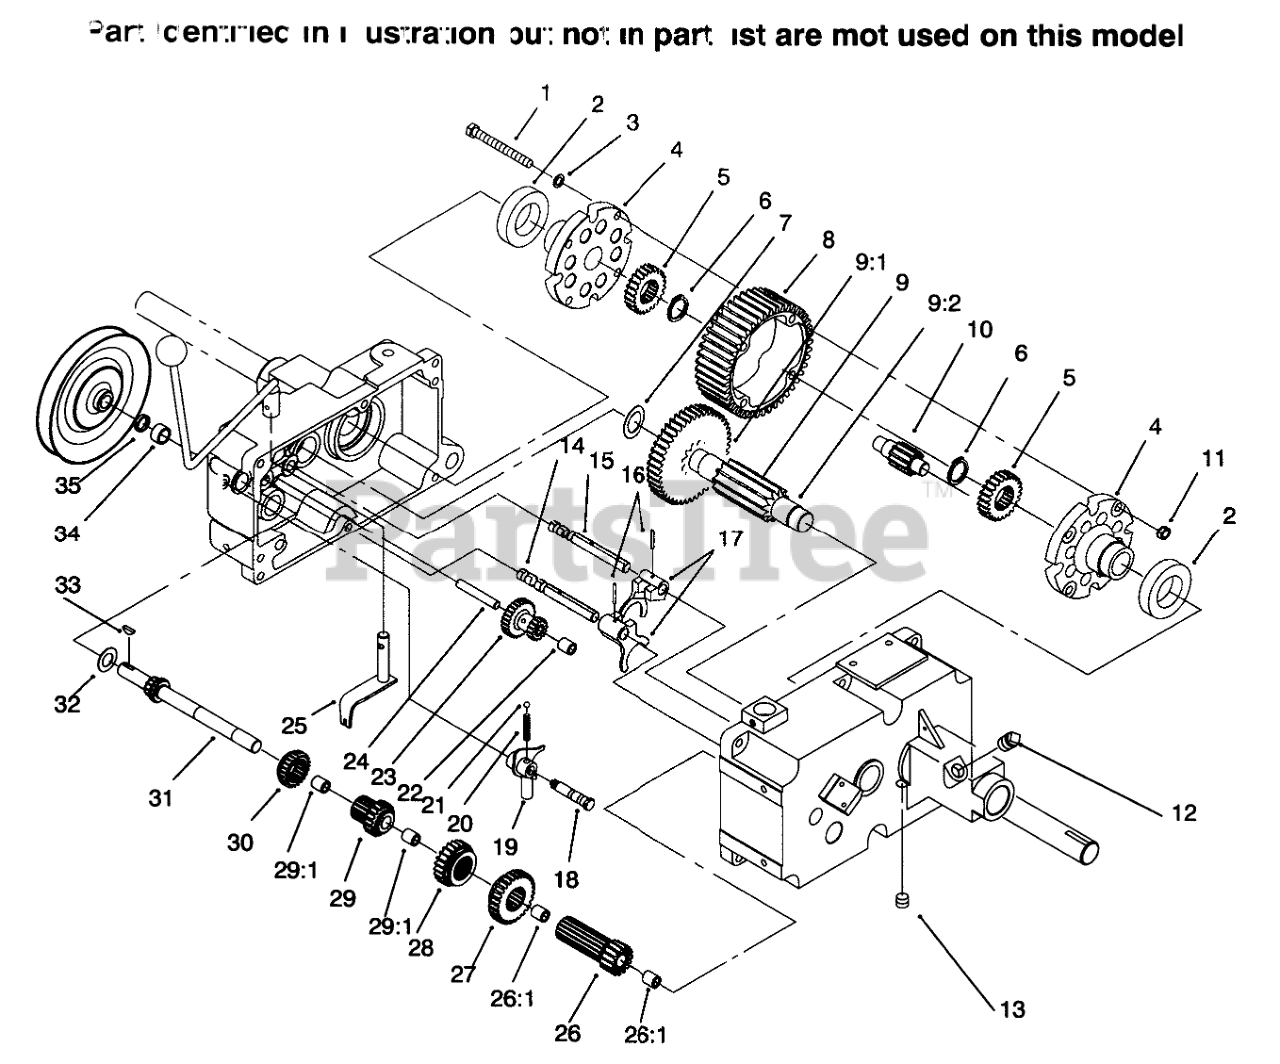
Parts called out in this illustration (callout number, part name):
1	BOLT-HEX
2	BEARING-BALL
3	WASHER
4	END CAP-DIFFERENTIAL
5	GEAR-AXLE DIFFERENTIAL
6	RING-SNAP
7	WASHER-THRUST
8	GEAR-DIFFERENTIAL RING, 43T
9	GEAR ASM
9:2	PINION SHAFT
10	GEAR-PINION, 11T
12	PLUG-PIPE, SQH
14	RAIL-SHIFT
15	RAIL-REAR SHIFT
16	PIN-ROLL
17	FORK-SHIFT
18	BOLT-DETENT
19	SHIFT FORK ASM
19	Shift Fork
20	SPRING-SHIFT STOP
21	BALL-DETENT
22	BEARING-NEEDLE
23	Gear
24	GEAR-SHAFT REDUCTION
25	SHIFT ASM
25:1	Shift Lever
25:2	Shaft-Lever
26	GEAR
26:1	BEARING-NEEDLE
27	GEAR-LOW AND REVERSE
28	GEAR-HI AND 2ND
29	Gear
29	GEAR
29:1	BEARING-NEEDLE
30	GEAR-SLIDING
31	SHAFT-INPUT
33	KEY-WOODRUFF
34	BEARING-NEEDLE
35	SEAL-OIL
58	WASHER-THR
